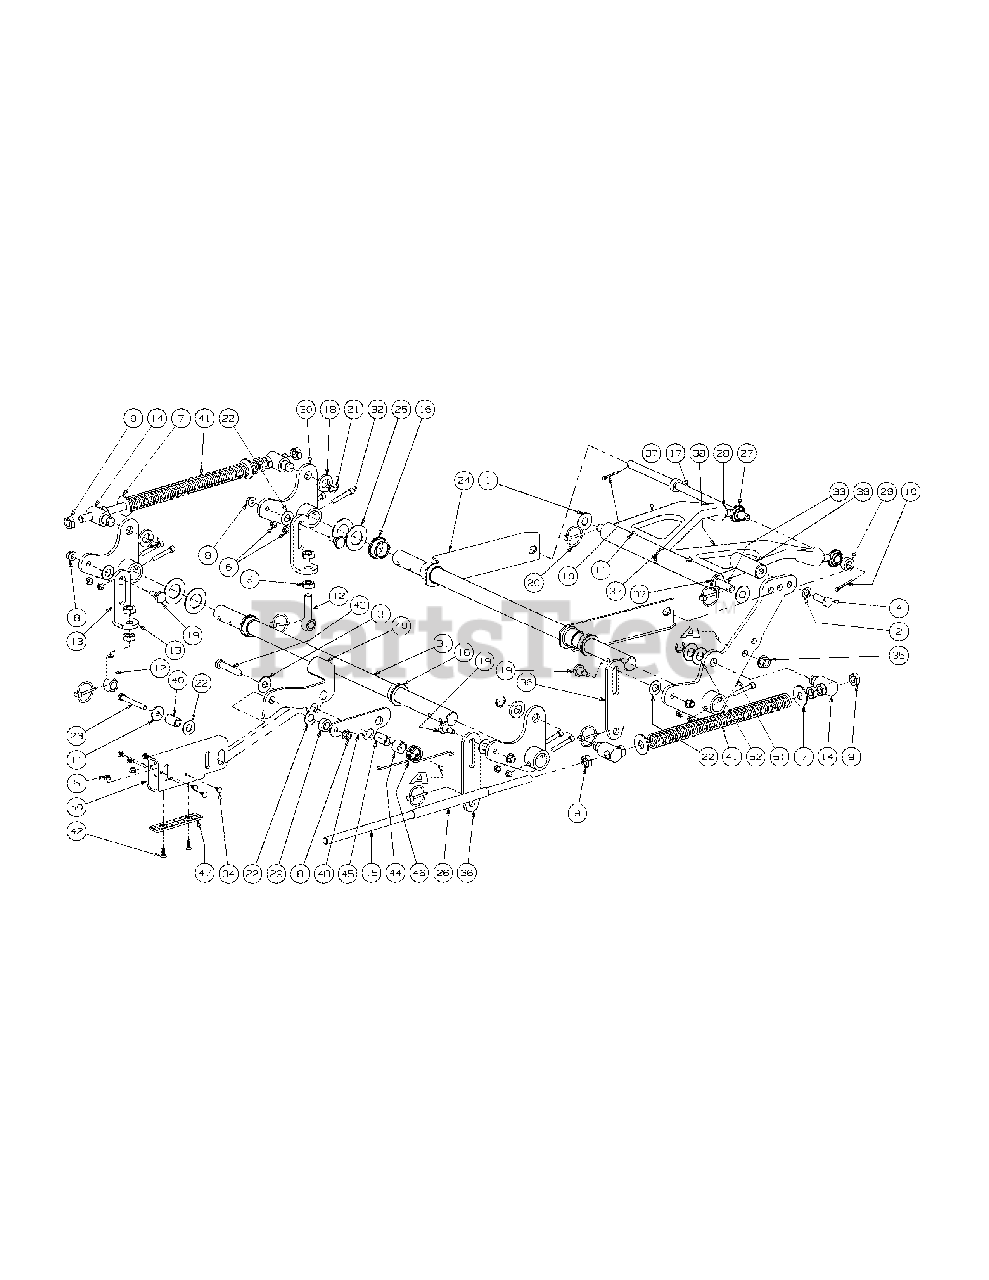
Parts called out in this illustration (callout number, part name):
1	Washer, 1.5 x .655 x .055
2	Lock Washer, 1/2
3	Flat Washer, .536 ID x .930 OD x .05
4	Hex Cap Screw, 1/2-13 x 1.50
5	Lock Nut w/Nylon Insert
6	Nut, 5/16-18, Nylock
7	Flat Washer, 5/8
8	Hex Nut, Flange Lock, 3/8-16
9	Jam Nut, 5/8-11
10	Cotter Pin, 3/16 x 1-1
11	Flat Washer, 1.25 x .411 x .100
12	Eye Bolt, 5/8ID
13	Eye Bolt Mount Link, 5/8 ID
14	Ferule Lift
15	Lift Connector Rod
16	Hex Flange Bearing, 1.25 ID
17	Front Lift Link, Rod Mount
18	Spacer, .812 ID x .268 Lg.
19	Shoulder Screw, 0.625 OD x .437 Lg.
20	Linch Pin, 3/16 Dia.
21	E Clip, 3/4 Dia.
22	Nylon Flat Washer, 5/8
23	HHCS, 3/8-16, 3.00
24	Front Frame Strut Assembly
25	Flat Washer, 1.25 ID
26	Hose, 5/8 ID 13/16 OD, 8" LG
27	Rod End, Male
28	Jam Nut, 5/8-18
29	Spacer, .630 ID x 1.06 OD x .440
30	Bellecrank Weldment Assembly
31	Deck Lift Shaft
32	Socket Head CapScrew, 5/16-18 x 2
33	Lift Link Rod
34	Rivet, 1/4 x 5/8
35	Nut, 1/2-13, FlangeLock
37	Bearing Lift Brace Assembly, Left Hand includes:
38	Bearing Lift Brace Assembly, Right Hand includes:
39	Deck Lift Foot Pedal
40	Spacer, .375 ID x .625 OD x 2.20
41	Lift Compression Spring
42	Flat Head Cap Screw, 1/4-20 x .75
43	HHCS, 1/2-13 x 2.50
44	Spacer, .76 ID x 1.0 OD x .75
45	Spacer, .51 ID x .75 OD x 1.240
46	Torsion Spring, .120 Wire x 1.32 OD
47	Lift Wear Plate
49	Lift Link Bracket
50	Lift Tube, 3.0 x 1.5
51	Deck Lift Foot Pedal Weldment
52	Washer, .76 x 1.49 x .06
